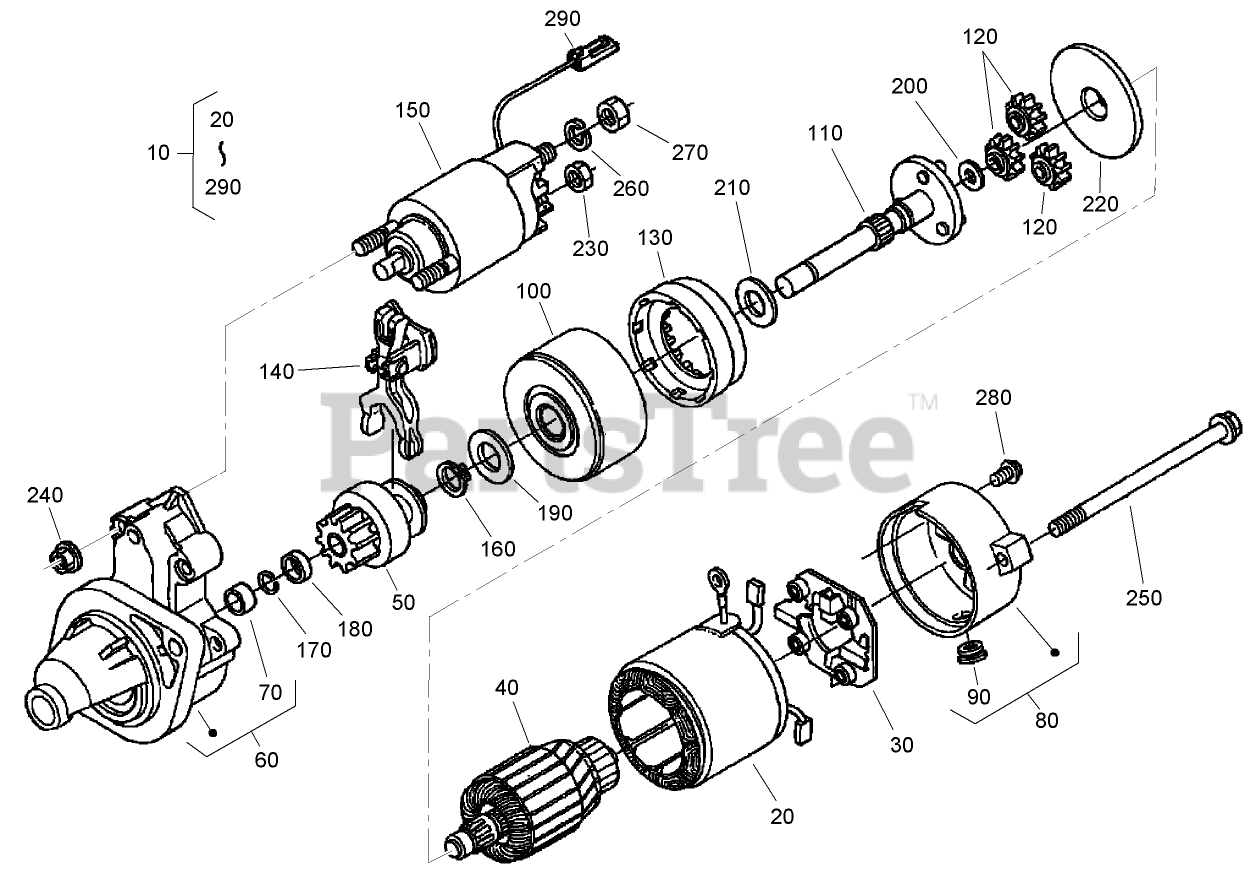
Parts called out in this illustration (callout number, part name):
10	STARTER ASM
20	STARTER YOKE ASM
30	HOLDER ASM
40	ARMATURE ASM
50	STARTER CLUTCH ASM
60	STARTER HOUSING ASM
70	BEARING
80	FRAME ASM
100	BEARING ASM
110	STARTER SHAFT ASM
150	MAGNETIC SWITCH ASM
160	RING-SNAP
170	RING-SNAP
180	COLLAR
190	WASHER-PLAIN
200	WASHER-PLAIN
210	WASHER-PLAIN
230	NUT-HEX
250	BOLT-THROUGH
260	WASHER-SPRING
270	NUT-HEX
290	WIRE-LEAD
